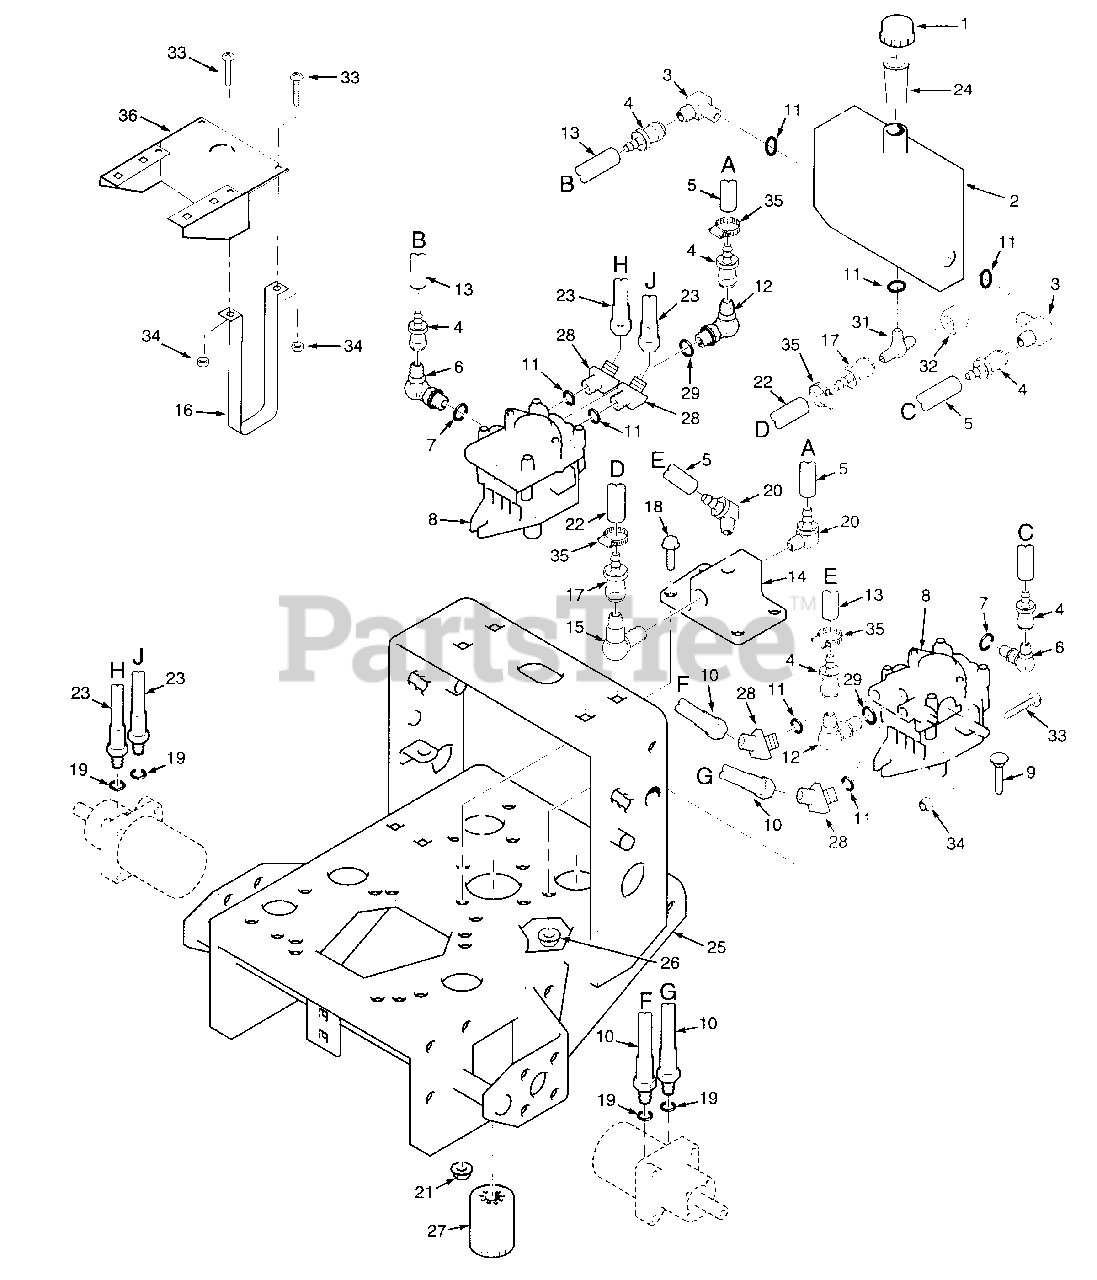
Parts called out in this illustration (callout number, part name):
1	Cap, Oil Reservoir
2	Oil Reservoir
3	Elbow, 90 deg. 7/16-20 x 9/16-18
4	Coupling, 7/16-20 SAE Flare Swivel to 1/4" Hose Push On
5	Hose, 1/4" ID - 7" Long
6	Elbow, 90 deg. 7/16-20 JIC to 9/16-18 "O" Ring
7	O-Ring
9	Bolt, Carriage, 3/8-16 x 1.25"
10	Hose, Pump to Wheel Motor
11	O-Ring
12	Elbow, 90 deg., 1/2 NPT
13	Hose, 1/4" ID - 5" Long
14	Oil Filter Base
15	Elbow, 90 deg. 1/2" NPT
16	Strap, Hydraulic Tank
17	Coupling, 3/4-16 SAE to 1/2" Hose Push On
18	Capscrew, 5/16-18 x .75" Serr. Flange
19	O-Ring
20	Elbow, 90 deg. Male 1/4 NPT to 1/4 Hose Push On
21	Nut, 5/16-18 Serr. Flange
22	Hose, Formed 1/2" ID
23	Hose, Pump to Wheel Motor
24	Tube, Filler Neck
25	Engine Deck (16" Wide) W/Decals
26	Nut, 3/8-16 Serr Flange
27	Oil Filter
28	Elbow, 45 Deg.-3/4-16 JIC Male x Male 3/4-16 O-Ring
29	O-Ring
31	T-Fitting, 1/2 (3/4-16)
32	Cap, 3/4-16
33	Screw, 1/4-20 x 2.0" Round Head Phillips
34	Nut, 1/4-20
35	Clamp, .87 max dia.
36	Bracket, Hydraulic Tank
